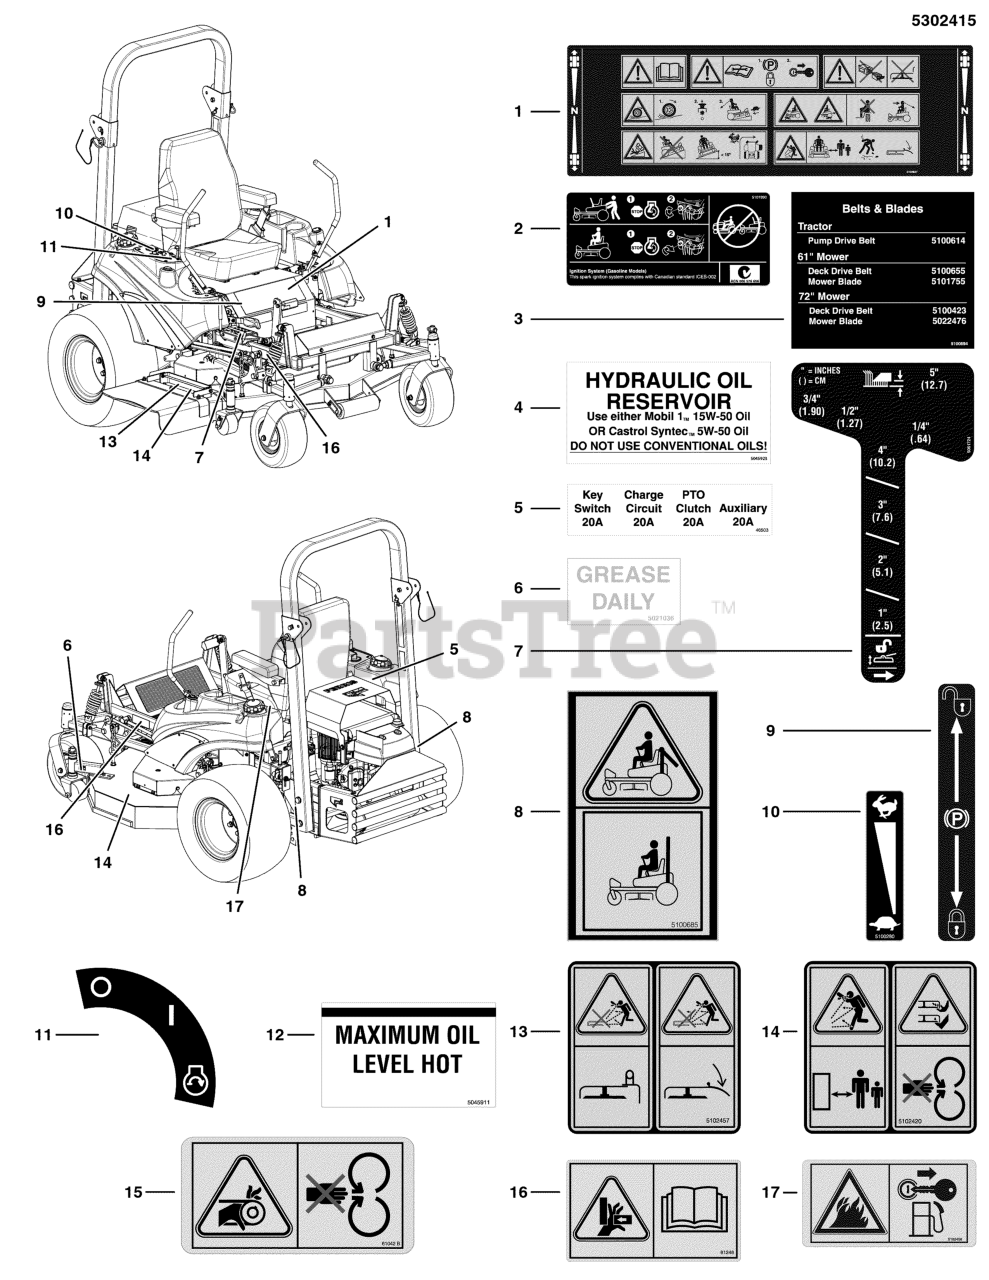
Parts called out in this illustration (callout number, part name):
1	DECAL, MAIN SAFETY, ANSI CE
2	DECAL, CZT HYRDO RELEASE
4	DECAL, OIL RESERVOIR
5	DECAL, FUSE LOCATION
6	DECAL, GREASE DAILY
7	DECAL, HEIGHT CITATION
8	DECAL, WARNING, ROLL BAR, CE
9	DECAL, PARKING BRAKE SYMBOLS
10	DECAL, THROTTLE CONTROL
11	DECAL, IGNITION SWITCH
12	DECAL, MAX OIL LEVEL
13	DECAL, DANGER DISCHARGE ANSI EXPORT
14	DECAL, DANGER, MOWER DECK, ANSI EXP
15	DECAL, CE, DANGER
16	DECAL, PINCH POINT, CE
17	DECAL, FIRE ANSI EXPORT
18	DECAL, SAFETY, CE ROPS
19	DECAL, SAFETY, CE ROPS, OBS
